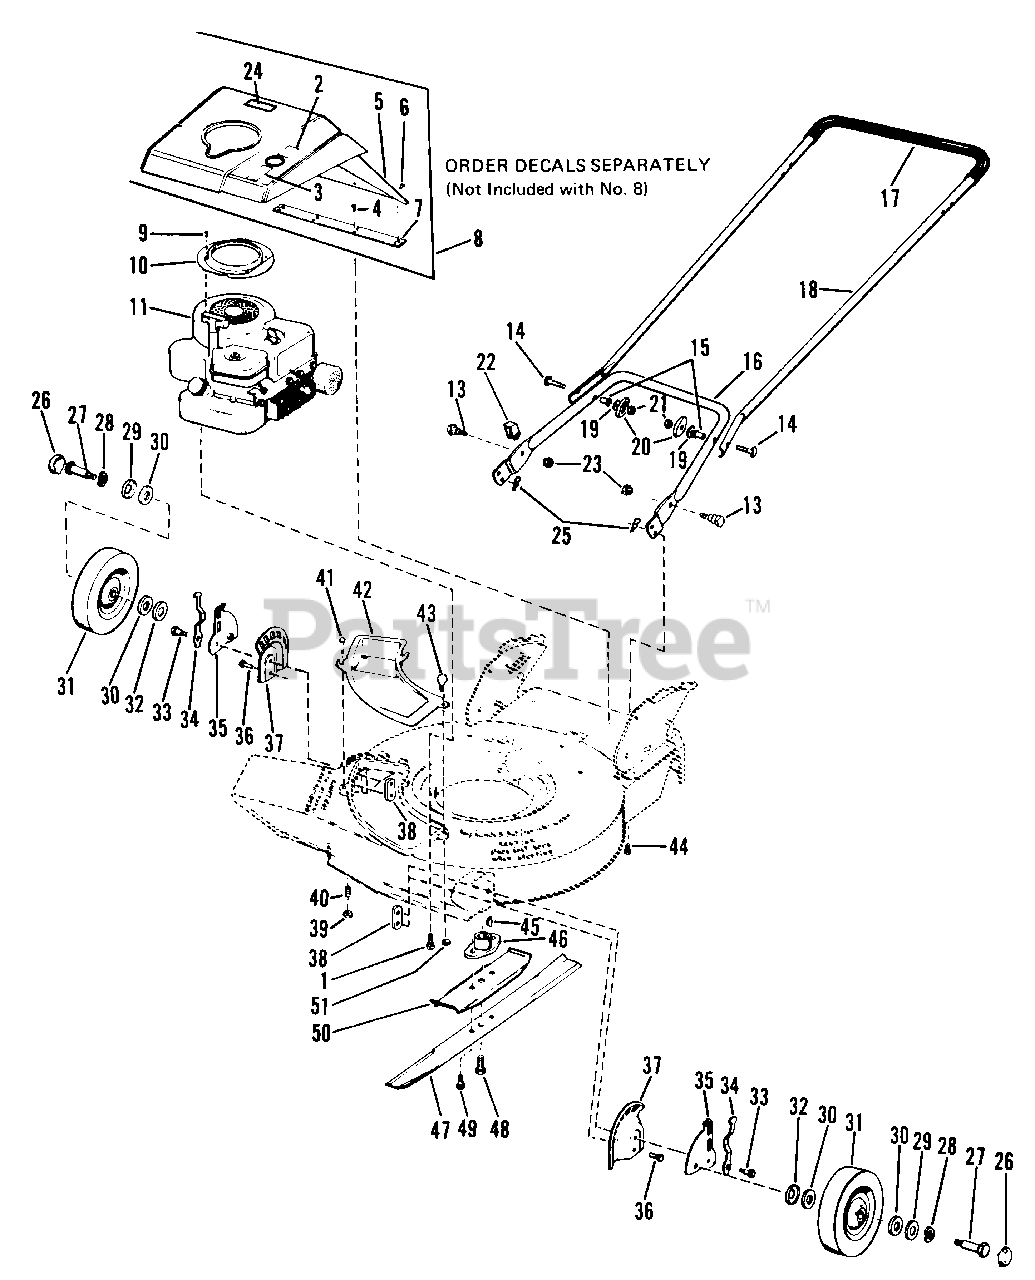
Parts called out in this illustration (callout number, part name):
1	SCREW, Thd. Forming, 3/8-16 x 1
2	FILM, Throttle Control
3	FILM, Caution
4	SCREW, Thd. Forming, #12-24 x 1-1/2
6	RIVET, Oval Hd, 3/16 x 5/16
8	SHROUD ASSY
9	RING, Pop Rivet
10	RING, Support (elec. start models only)
13	BOLT, Latch Handle
13	BOLT, Shoulder, Hex
14	BOLT, Curved Hd., 5/16-18 x 1-3/4
15	EYELET, Handle
16	HANDLE, Lower
17	TUBING, Handle
18	HANDLE, Upper
19	WASHER, Plain, 1/4
20	NUT, Wing
21	LOCKNUT, Full Hex, 5/16-18
22	LATCH, Handle
23	NUT, Latch Handle
24	FILM, Latch
25	CLIP, Hairpin
27	BOLT, Front Wheel
28	WASHER, Spring
28	WASHER, Wave
29	WASHER, Plain, 13/32 x 1-1/4
29	SEAL, Housing
30	SEAL (Mfg. No. 1690132, 133 only)
31	WHEEL, 6" Front
32	SEAL, Housing
33	BOLT, Shoulder, Hex
34	SPRING, Height Adj.
35	ADJUSTER, Height Front
36	CAPSCREW, Hex, 3/8-16 x 5/8
37	PLATE, Adjusting
38	NUT, Pilot Twin
39	LOCKNUT, Full, 1/4-20
41	SCREW, Special
42	PLATE, Cover
43	SCREW, Thumb, 1/4-20 x 5/8
44	SCREW, Thd. Forming, 1/4-20 x 3/8
45	KEY, Woodruff #6, 5/32 x 5/8
47	BLADE, 21"
48	CAPSCREW, Hex, 3/8-24 x 1-1/2
49	BOLT, Blade to Adapt. 5/16-18 x 1
50	STIFFENER, Blade
51	NUT, Speed Special
